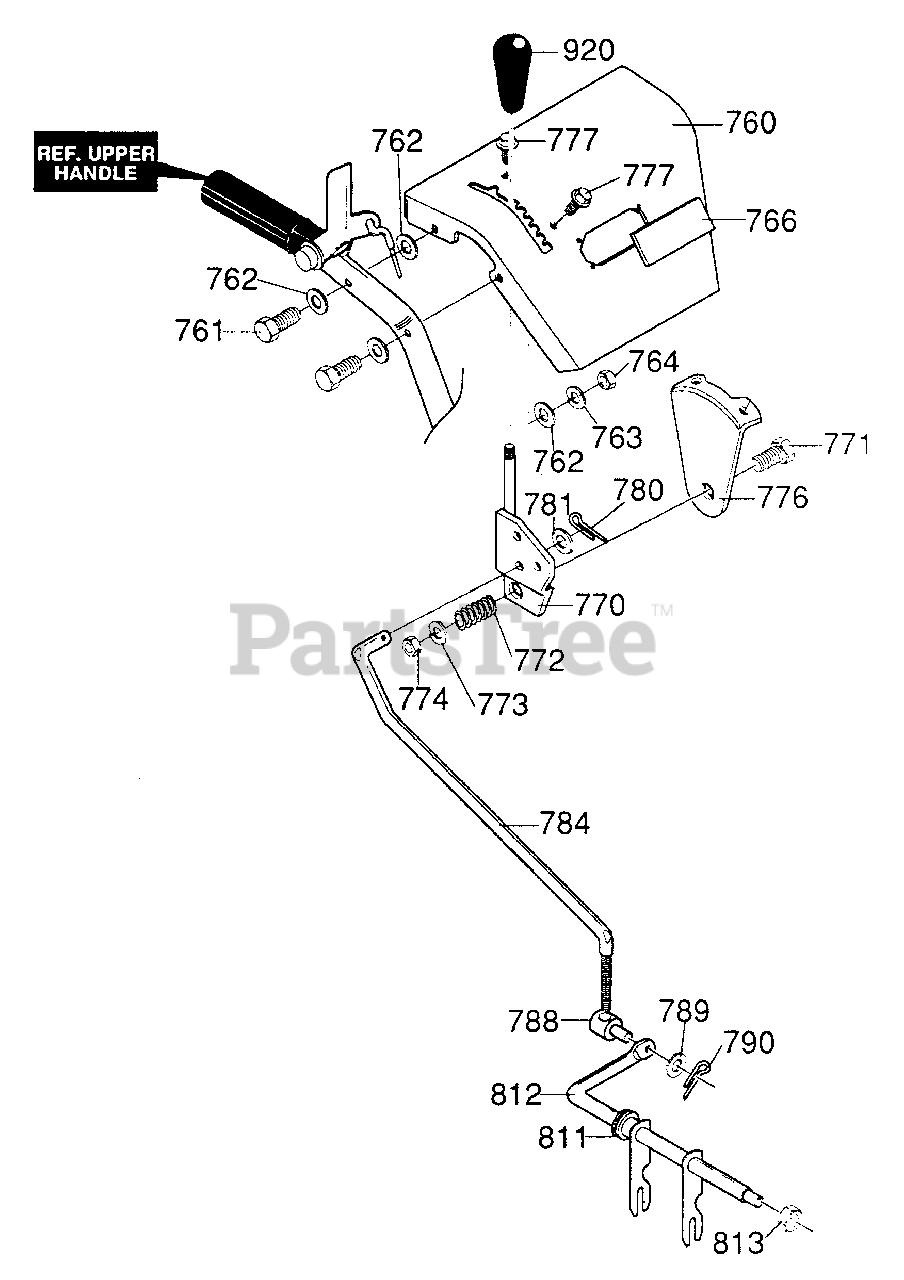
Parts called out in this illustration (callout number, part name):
760	PANEL, CONTROL BS W/LGT
761	SCREW, 5/16-18 x 1.75 HHC
762	FLATWASHER, .344 x .69 x .065
763	WASHER, HVSPTLK .328 x .60 x .09
764	NUT, 5/16-18 REGHEX
766	PLATE, PANEL
770	HANDLE, ASSY SPEED CONTROL
771	SCREW, 3/8-16 x 2.00
773	FLATWASHER, .406 x .81 x.065
774	NUT, 3/8-16 HEXNYL
776	BRACKET, SPEED CONTROL
777	SCREW, 5/16-18 x .75 WAHHTAP
780	PIN, COTTER. 090 DIA x .75LG
781	FLATWASHER, .344 x .69 x .065
784	ROD, SPEED CONTROL
788	NUT, TRUNION 5/16-24
789	FLATWASHER, .344 x .69 x .065
790	PIN, COTTER .090 DIA x .75 LONG
811	BEARING, FL .500 ID x .88 OD x .31
812	ROD, ASM SPEED CONSOLE
813	NUT, 3/8-16 REGHXCTRLK
920	KNOB, 3/8-16 x .75
